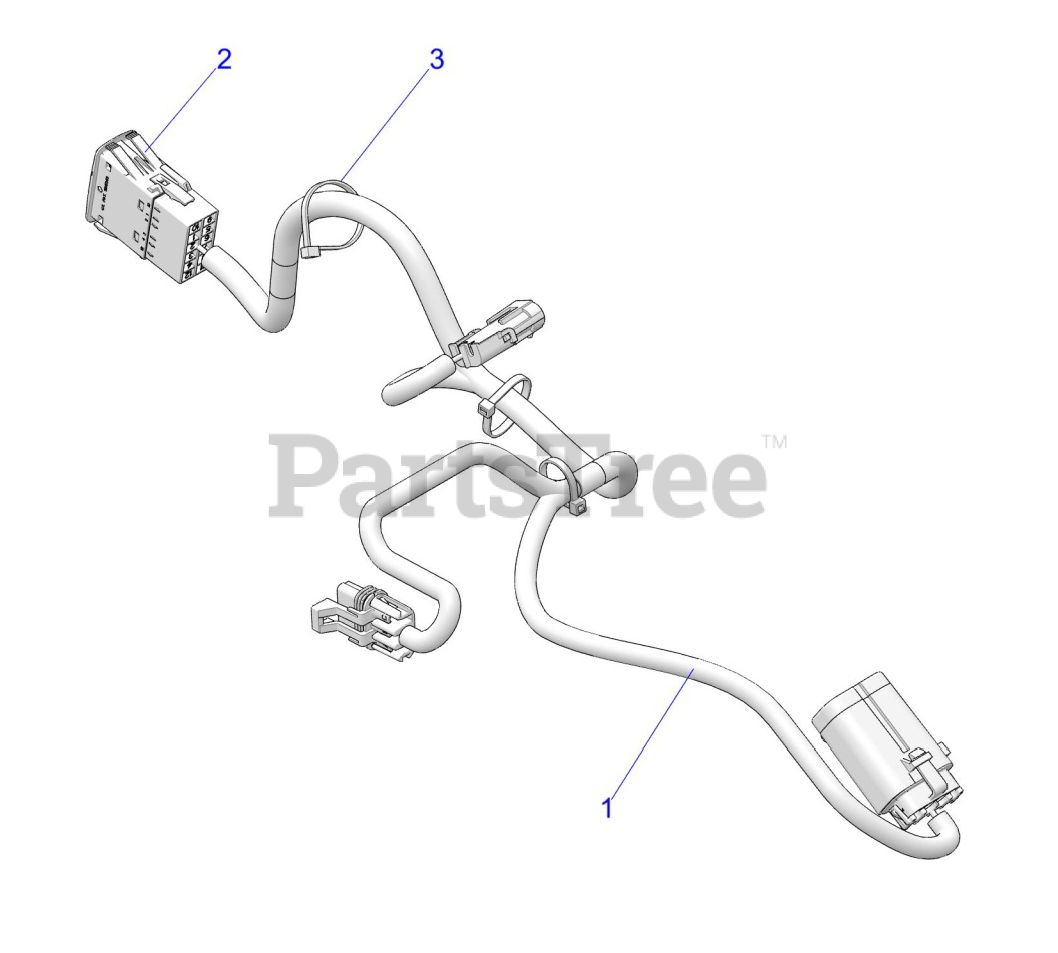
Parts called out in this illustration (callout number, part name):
1	HARNESS-BOX LIFT,ZS
2	SWITCH-BOX LIFT
3	CABLE TIE (10)
